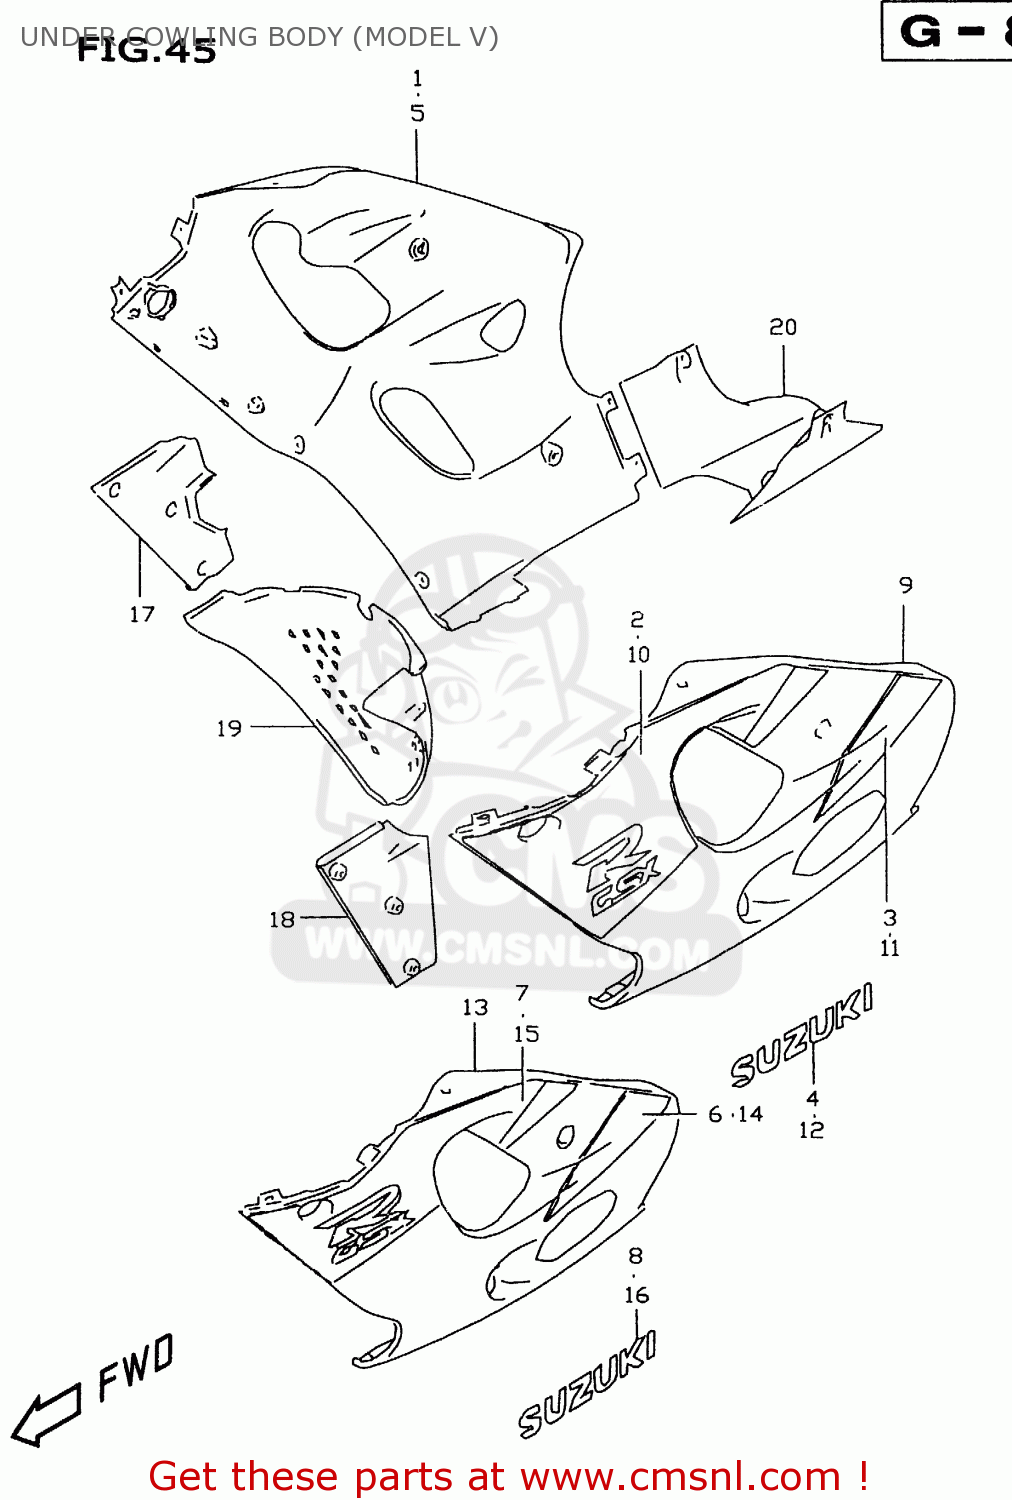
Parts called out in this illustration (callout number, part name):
1	COWLING ASSY,UNDER,R
2	TAPE SET,UNDER COWLING,R
3	TAPE,COWL UNDER LWR,R
4	EMBLEM,SUZUKI(BLACK)
5	COWLING ASSY,UNDER,R
6	TAPE,COWL UNDER LWR,R
7	TAPE SET,UNDER COWLING,R
8	EMBLEM,SUZUKI(WHITE)
9	COWLING ASSY,UNDER,L
10	TAPE SET,UNDER COWLING,L
11	TAPE,COWL UNDER LWR,L
12	EMBLEM,SUZUKI(BLACK)
13	COWLING ASSEMBLY,UNDER,LEFT
14	TAPE,COWL UNDER LWR,L
15	TAPE SET,UNDER COWLING,L
16	EMBLEM,SUZUKI(WHITE)
17	COWLING,UNDER INNER,R
18	COWLING,UNDER,INNER,LEFT
19	COWLING,UNDER,CENTER
20	COWLING ASSEMBLY,UNDER,REAR
